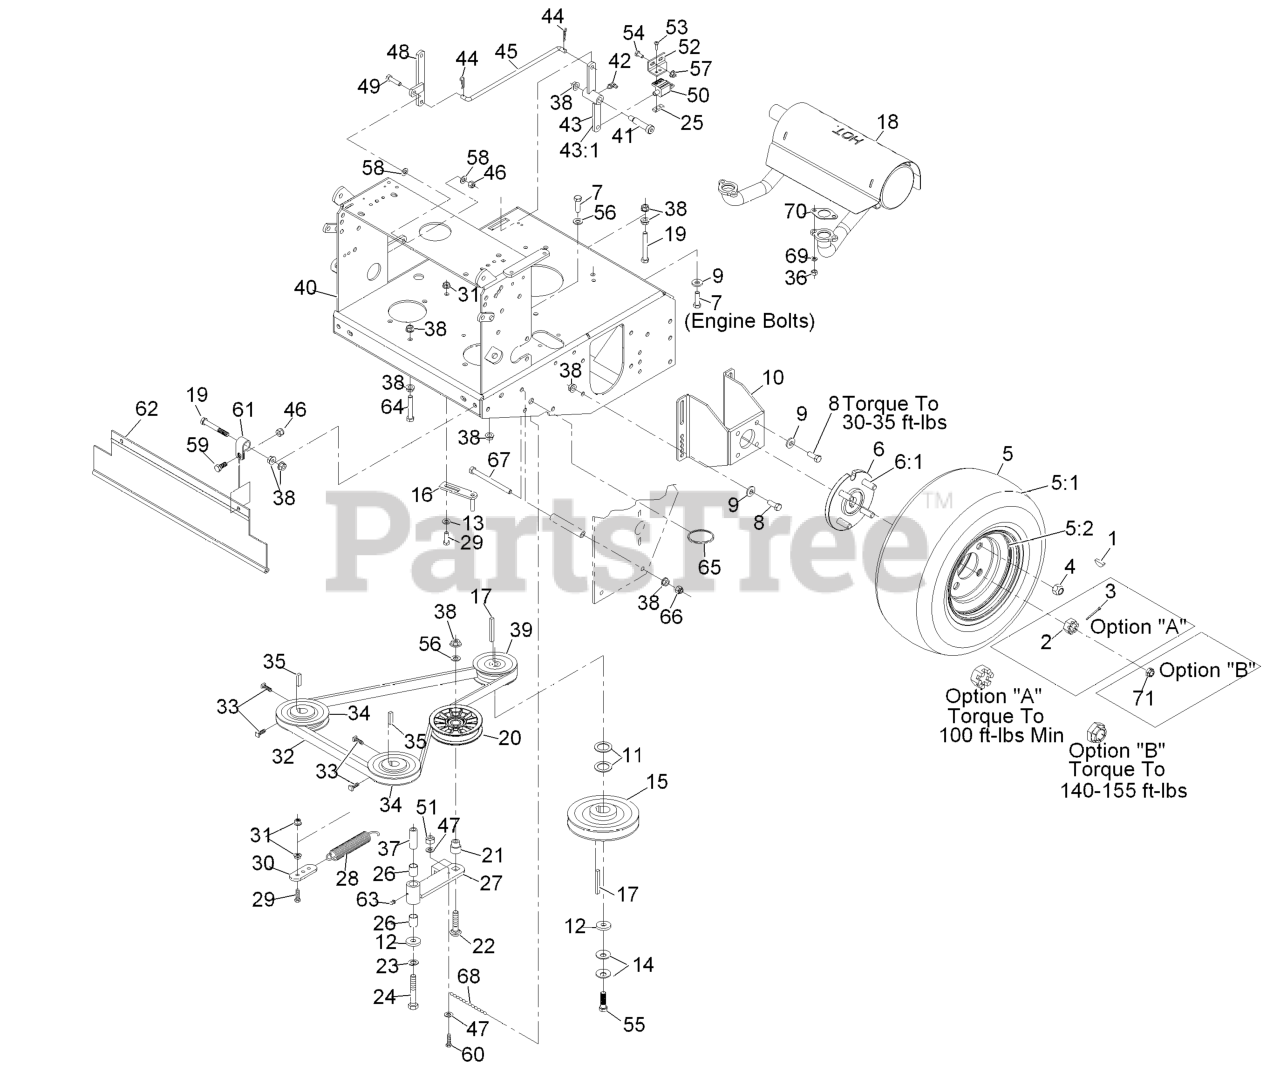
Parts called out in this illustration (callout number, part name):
1	KEY-WOODRUFF
2	NUT-HEX, SLOTTED
3	PIN-COTTER
4	NUT-LUG
5	WHEEL AND TIRE ASM
5:1	TIRE-TURFMASTER
5:2	RIM-WHEEL
6	WHEEL HUB ASM
6:1	STUD-WHEEL
7	SCREW-HH
8	SCREW-HH
9	WASHER-BELLEVILLE
10	MOUNT-MOTOR
11	WASHER-SPACER
13	WASHER-SPRING
14	WASHER-SPRING
16	GUIDE-BELT
18	MUFFLER,HORIZONTAL
19	SCREW-HH
20	PULLEY-IDLER, FLAT
21	BUSHING-IDLER
22	SCREW-CARR
23	WASHER-LOCK
24	BOLT-CARR
25	PLATE-TAPPED
26	SLEEVE-BEARING
27	IDLER ARM ASM
28	SPRING-EXTENSION
29	SCREW-HH
30	ANCHOR-SPRING
32	BELT-COG
33	SCREW-SET
34	SHEAVE ASM
37	BUSHING
38	NUT-HHF, WHIZ
39	PULLEY
40	DECK,ENGINE W/DECALS
42	FITTING-GREASE, 90 DEG
43	BELLCRANK ASM
44	PIN-COTTER
45	LINKAGE-ENGAGE, BLADE
46	NUT-LOCK, NI
47	WASHER-FLAT
49	SCREW-HH
50	SWITCH-OPEN, NORMALLY
51	NUT-LOCK, NI
52	BRACKET-SWITCH, BLADE
53	SCREW-PPH
54	SCREW-HH
55	SCREW-HH
56	WASHER-FLAT
58	WASHER-PLAIN
59	SCREW-HH
60	SCREW-HSH
61	CLIP-LOOM
62	SHIELD-DRAG
63	FITTING-GREASE
64	SCREW-HH
65	RING-SPLIT
66	NUT-LOCK, NI
67	SCREW-HH
68	CHAIN-LINK, TWIST
69	WASHER-LOCK
70	GASKET-EXHAUST
71	NUT-LOCK
